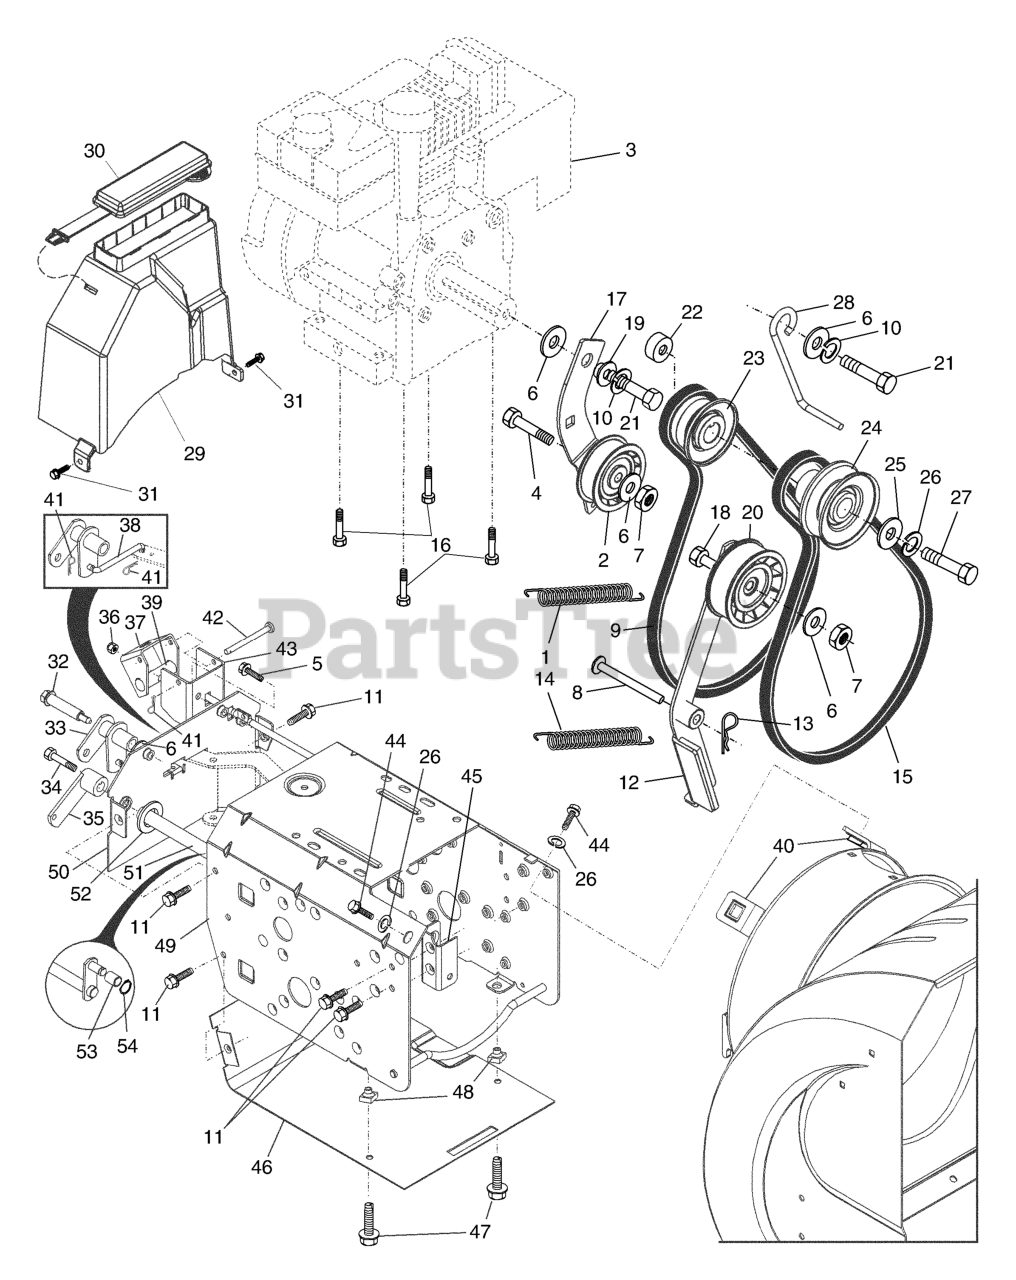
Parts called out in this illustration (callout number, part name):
1	RP SPRING, TRACTION IDLER
2	PULLEY.W/SPACER.2.25
4	BOLT.5/16-18X1-1/4 FULL.THREAD
5	SELF-TAPPING SCREW 5/16-18X3/4
6	STEEL WASHER
7	NUT.CENTERLOCK.5/16-
8	PIN, IDLER PIVOT
9	V-BELT, TRACTION DRIVE
10	WASHER.LOCK.HVY.HLCL.SPR.5/16
11	Screw, Hex Head 5/16-18 x 1/2
12	ARM ASSEMBLY, IMPELLER IDLER
13	RETAINER CLIP PM
14	SPRING, BRAKE
15	V-BELT, IMPELLER DRIVE
16	BOLT 3/8-16X1-1/8
17	IDLER ARM
18	HEX BOLT
19	RP BUSHING, IDLER PIVOT
20	PULLEY.W/SPACER.2.75
22	SPACER, ENGINE PULLEY
23	PULLEY,ENGINE TRACTION DRIVE
24	PULLEY, ENGINE IMPELLER DRIVE
26	LOCKWASHER
27	SCREW, HEX HD 3/8-24 X 1-3/8
28	GUIDE, BELT
29	BELT COVER
30	COVER.STORAGE.SNOW
31	SCREW
32	BOLT, SHOULDER 5/16-18
33	BELLCRANK SHIFTER
35	ARM, AUGER CONTROL
36	NUT.71038.31-18.HEX.NYLOCK
37	BRACKET, PIVOT
38	LINK, SPEED CONTROL
39	TRUNION, PIVOT BRACKET
40	NUT, CAGE 3/8-16
41	RETAINER CLIP
42	PIN, PIVOT BRACKET
44	BOLT
45	BRACKET, IDLER PIVOT
46	PAN, FRAME BOTTOM
47	Screw, Hex Head 5/16-18 x 3/4
48	NUT.SPEED.5/16-18
49	FRAME ASSY
50	PLATE, FRAME END
51	SHAFT, AUGER CONTROL
52	THRUST WASHER
53	ROLLER.ACTUATOR
54	RETAINING RING
